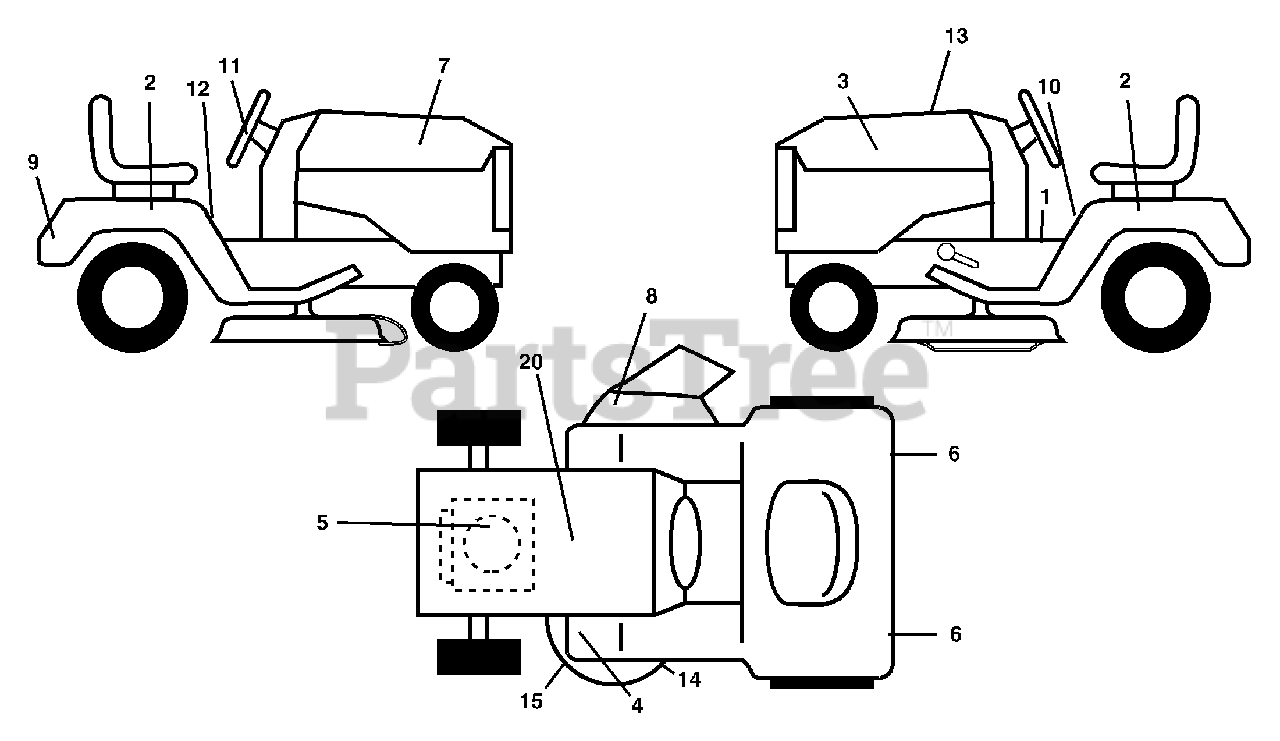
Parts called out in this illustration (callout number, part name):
1	Decal Dash
2	Decal Fender Auto
3	Decal Hood LH
4	Decal Footrest
5	Decal HP Engine
6	Reflector Tail Light
7	Decal Hood Rh
8	Decal Warning Mower
9	Decal Fender Logo
10	Decal Fender Danger E/F
11	Decal Ins Strg Whl
12	Decal Brake Parking
13	Decal Replace Part
14	Decal V-Belt Schematic
15	Decal Deck Caution
20	Decal Bat Dan/Psn
